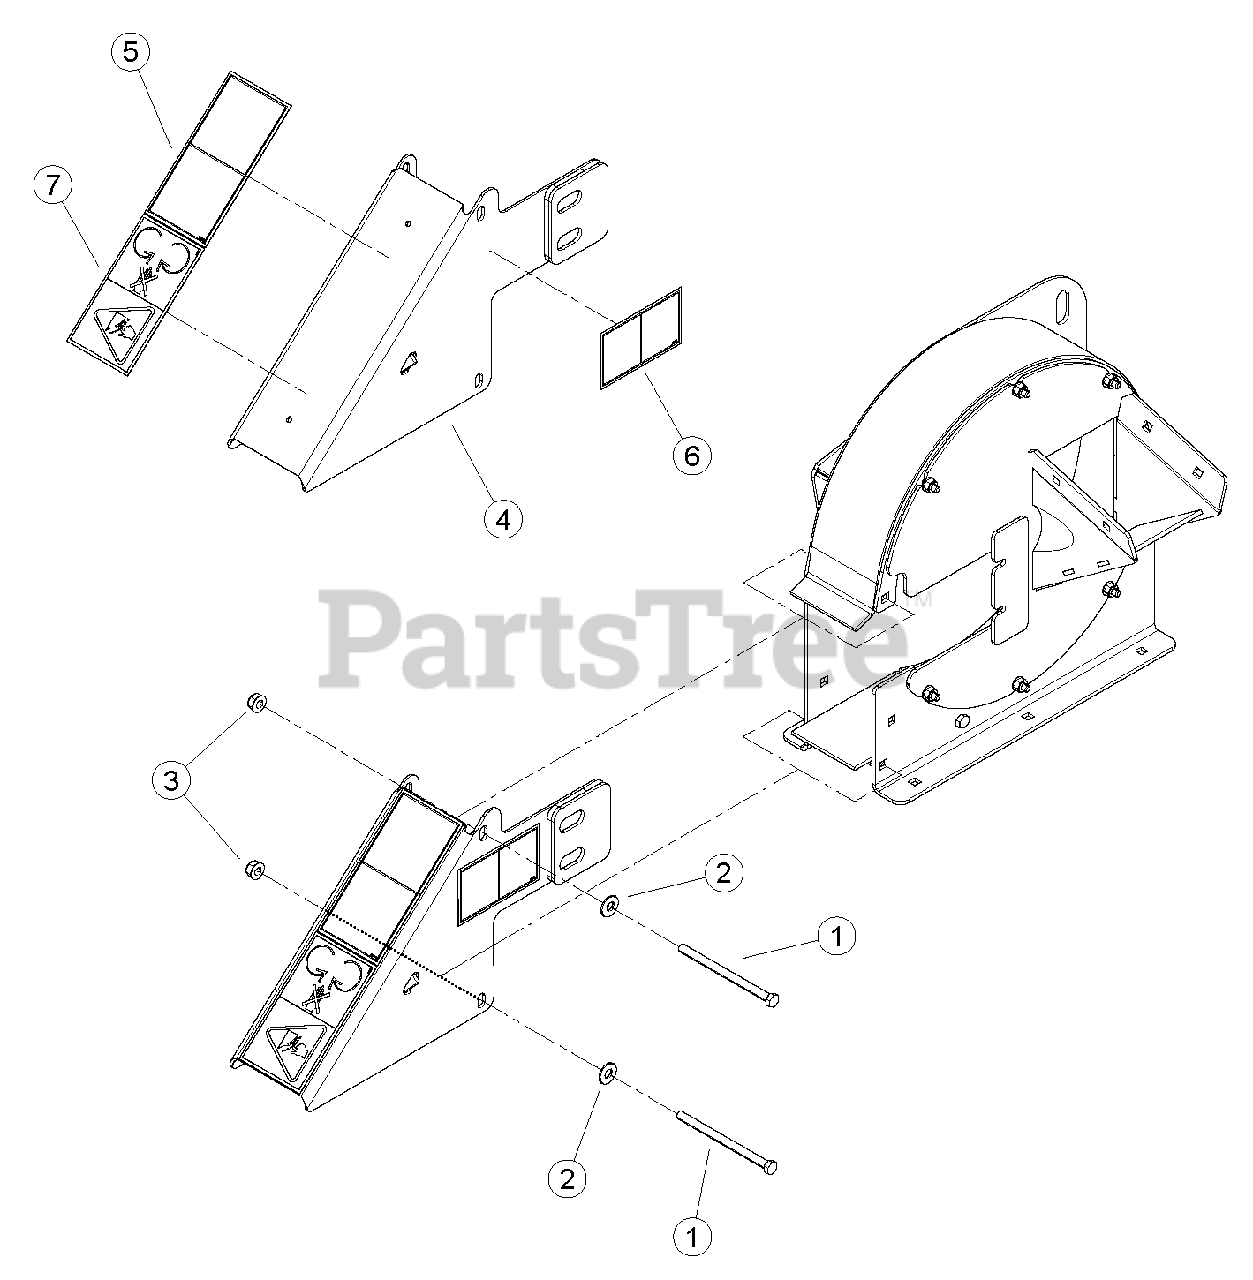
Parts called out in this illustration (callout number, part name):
1	BOLT, 3/8 X 5-1/2 HEX HD GR5 ZP
2	WASHER, 3/8 FLAT ZP
3	NUT, 3/8-16 NYLOCK FLANGE
4	ASSEMBLY, DISCHARGE CAP
5	DECAL, KNIFE ACCESS ISO
6	DECAL, DISCHARGE ISO
7	DECAL, BLADE DANGER ISO
